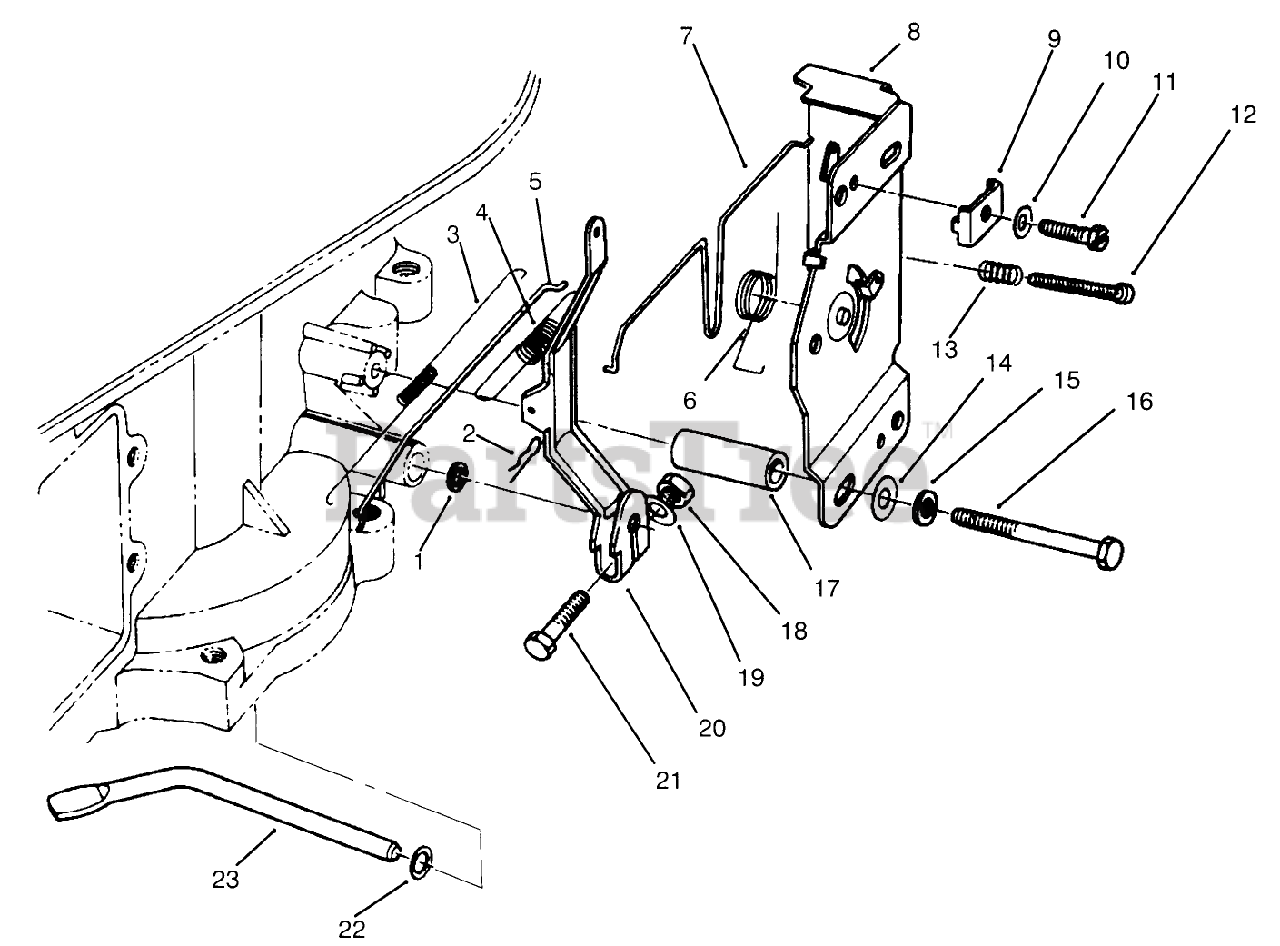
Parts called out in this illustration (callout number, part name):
1	SEAL-OIL (VC6X10X2.6)
2	Pin-Snap (1.2 X 21.2)
3	Spring
4	Spring
5	Link
6	Spring
7	LINK-Choke
8	Panel Incl #2 4-7
9	Clamp
10	Washer
11	Bolt
12	Screw
13	Spring
14	Washer
15	Washer
16	Bolt
17	Collar
18	NUT-HEX (6mm)
19	Washer-Plain (6mm)
20	Arm ASM
21	Bolt (6X28)
22	Washer
23	Arm-Pivot
